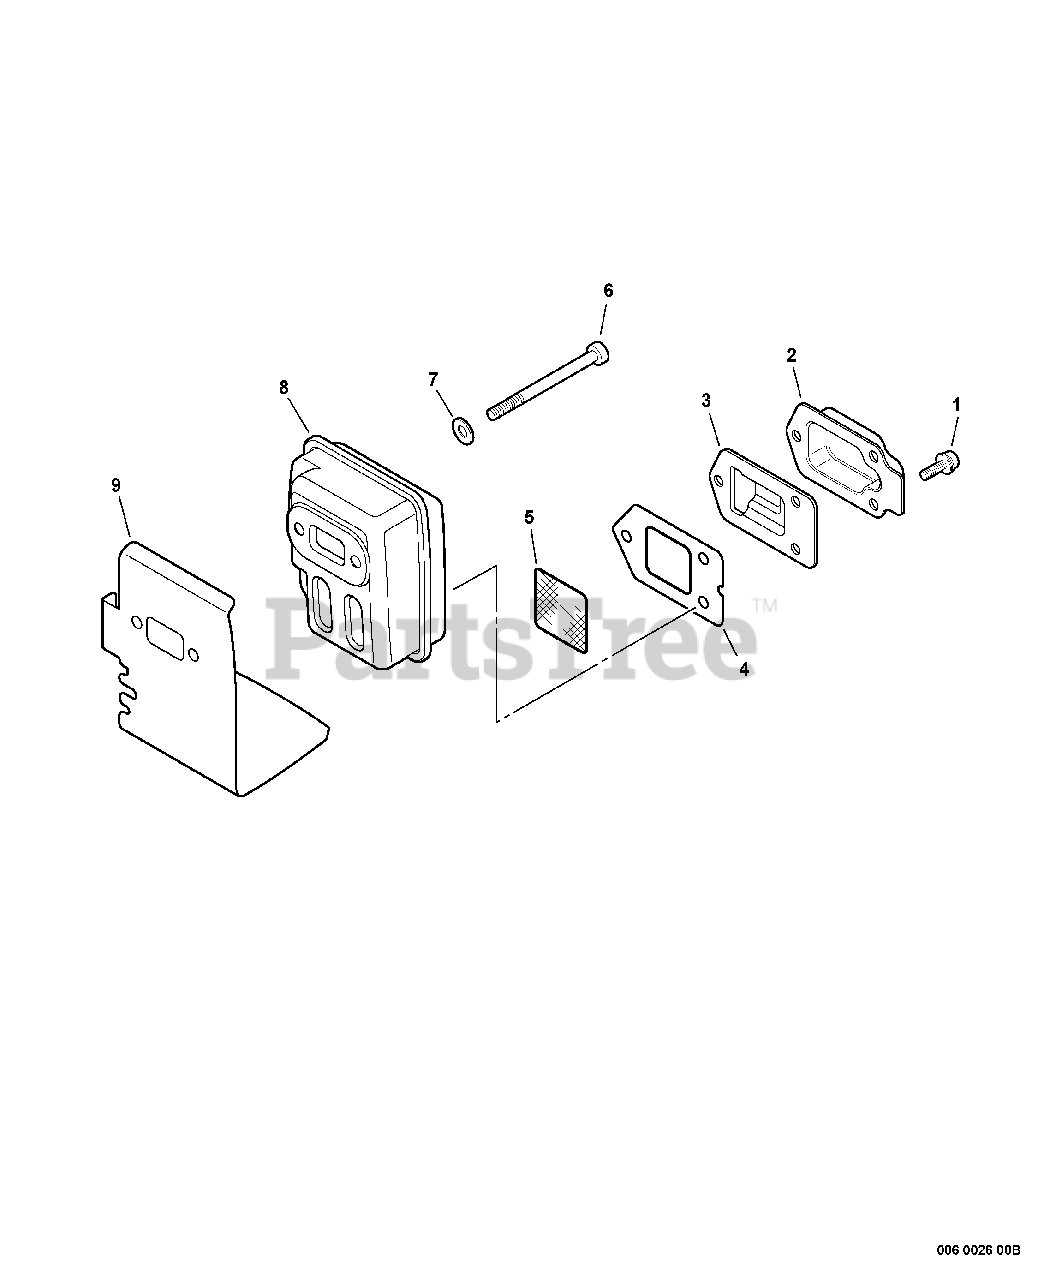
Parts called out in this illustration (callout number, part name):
1	SCREW 4×10
2	GUIDE, EXHAUST - INNER
3	GUIDE, EXHAUST - INNER
4	GASKET, EXHAUST
5	SCREEN, SPARK ARRESTER
6	BOLT 5×55
7	WASHER, FLAT 5.5×10×0.8
9	HEAT SHIELD, EXHAUST
